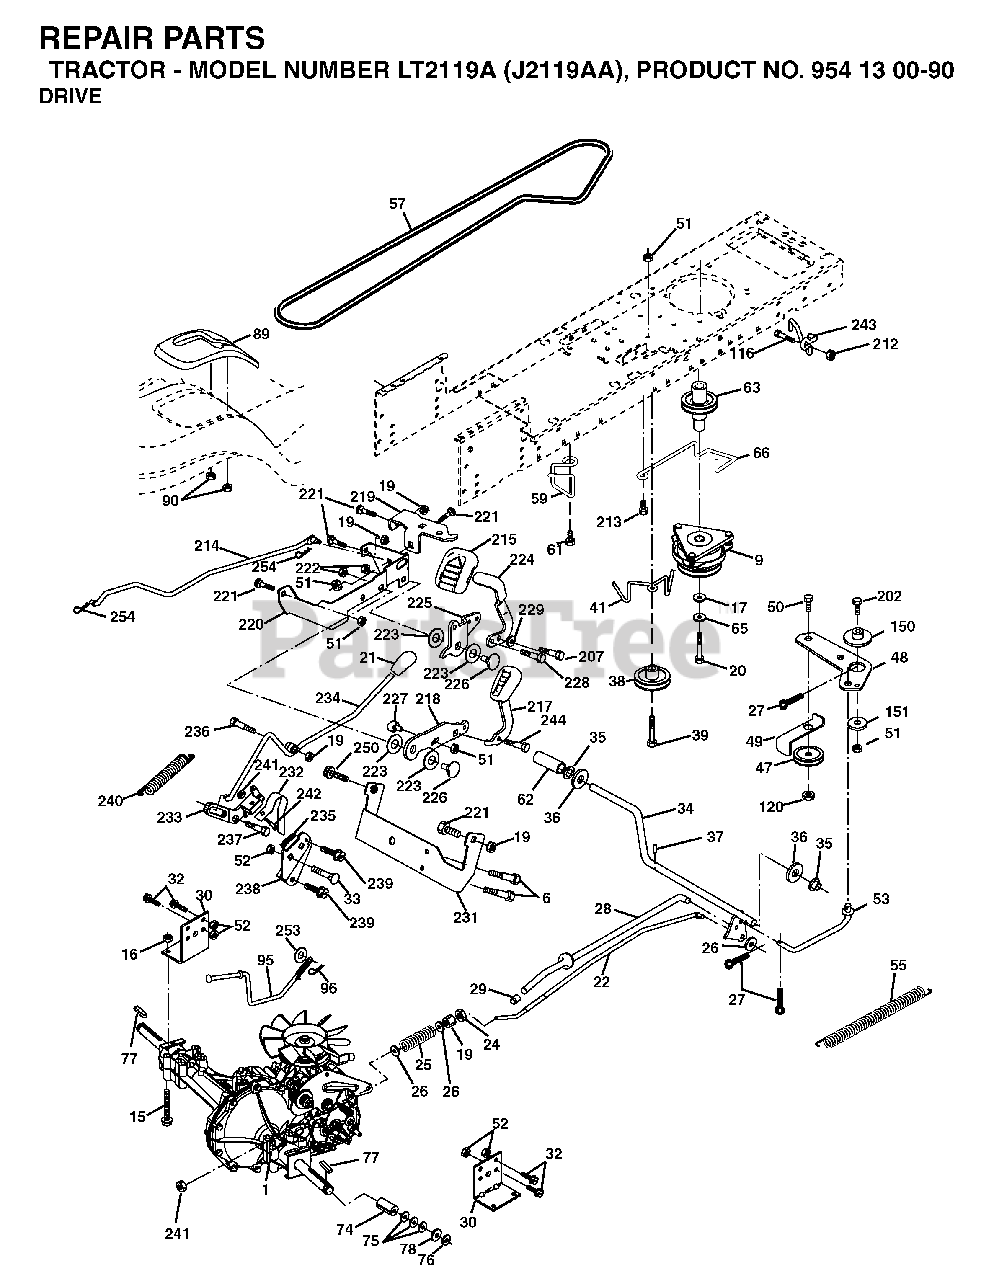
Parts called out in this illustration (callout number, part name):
6	SCREW 5/16"
9	CLUTCH ELECTRIC
15	BOLT HEX 5/16-18 GR 5
16	NUT.71038.31-18.HEX.NYLOCK
19	NUT
20	BOLT HEX 7/16-20X4-1/4"
22	ROD, BRAKE
24	NUT
25	SPRING ROD LT
27	COTTER PIN
28	ROD, PARKING BRAKE
29	PLUNGER CAP
30	BRKT, TRNSXLE MNT 20"
32	BOLT
33	BOLT
34	SHAFT, FOOT PEDAL
35	BEARING.NYLON
36	WASHER LT
37	DRIVE PIN
38	PULLEY IDLER COMPOSITE
39	BOLT
41	KEEPER, BELT IDLER
47	IDLER PULLEY
48	BELLCRANK, CLUTCH
49	RETAIN BELT
50	BOLT.3/8-16X1.50
51	LOCKNUT
52	LOCKNUT
53	LINK, CLUTCH LT
55	SPRING, RETURN LT
56	SCREW.3/8-16
57	DRIVE BELT, LTH & YTH TRACTORS
59	KEEPER, BELT CENTER
61	SCREW 3/8-16X.875
62	PEDAL COVER T
63	PULLEY- ENGINE
65	LOCKWASHER
66	KEEPER BELT ENGINE
74	SPACER AXLE
76	E-RING LT
77	SQUARE KEY
95	ROD BYPASS
96	RETAINER M
116	BOLT D
120	NUT LOCK FLG 3/8-16 UNC
150	SPACER, RETAINER
151	WASHER 12/32X2X10GA
202	BOLT
207	SCREW, 5/16-18 X 1/2
212	NUT
213	SCREW.3/8-16
214	LINK TRANSAXLE
215	COVER PEDAL FORWARD
217	PEDAL REVERSE
218	ARM CONTROL PEDAL REVERSE
219	BRACKET FREST PDL
220	BRACKET MTG.PDL CONTROL
223	WASHER NYLON
224	PEDAL FORWARD
225	ARM CONTROL PEDAL FORWARD
226	BOLT PIVOT SPACER
227	CAM REVERSE PEDAL LT
228	BOLT SHOULDER
229	WASHER SERRATED
231	STRAP TORQUE
232	ACUATOR CRUISE DISENGAGE
233	PAWL CONTROL CRUISE
234	LEVER CONTROL CRUISE
235	SECTOR CONTROL CRUISE
237	SHOULDER BOLT 5/16-18TT
238	ARM MTG.CRUISE SECTOR
240	SPRING RETURN CRUISE CONTROL
241	NUT CENTERLOCK
242	BOLT
243	BRKT ASM MTNG
250	SCREW 3/8-16X3/4
254	CLIP RETAINER
